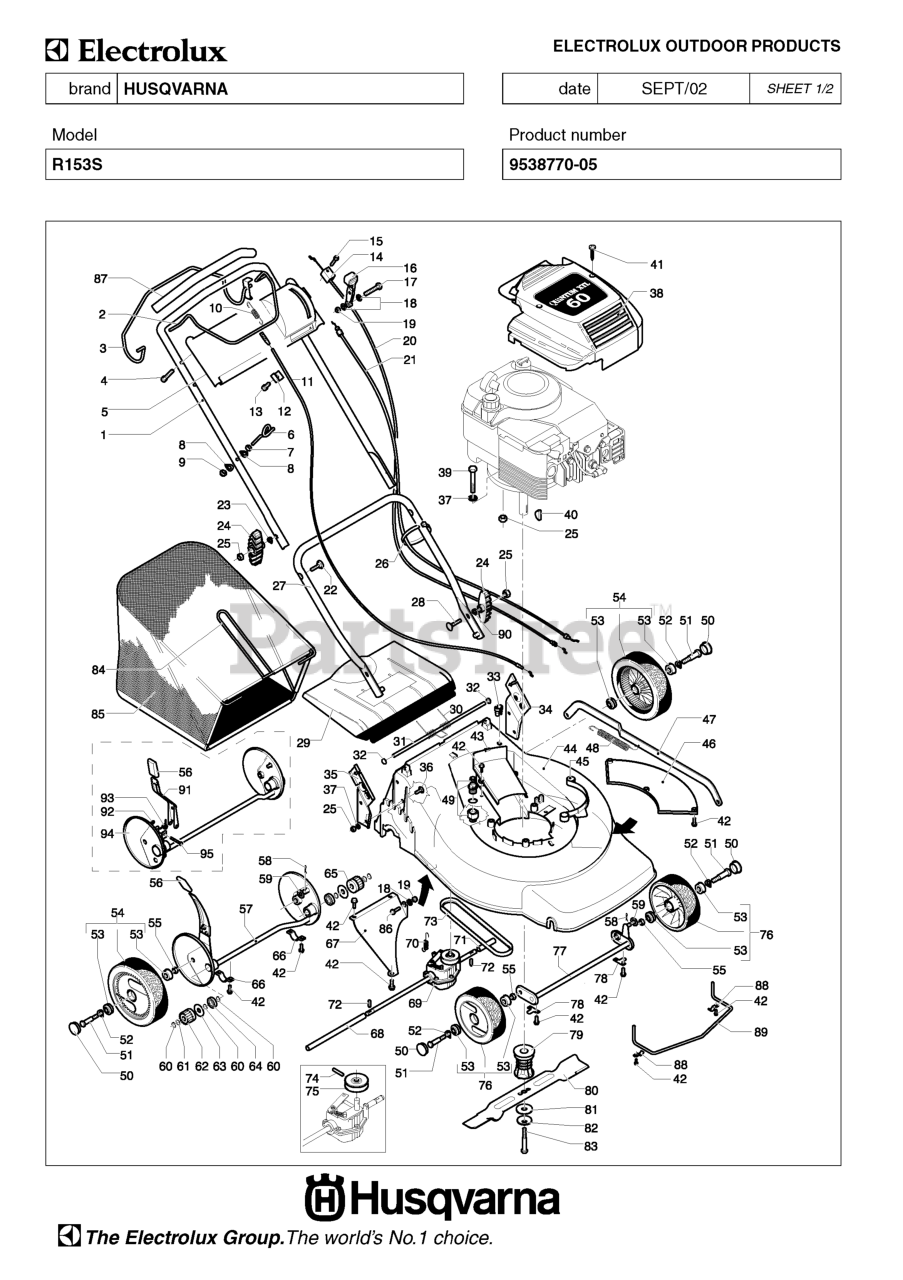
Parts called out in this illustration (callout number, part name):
28	Screws
42	Screws
58	Pins
60	Washers
